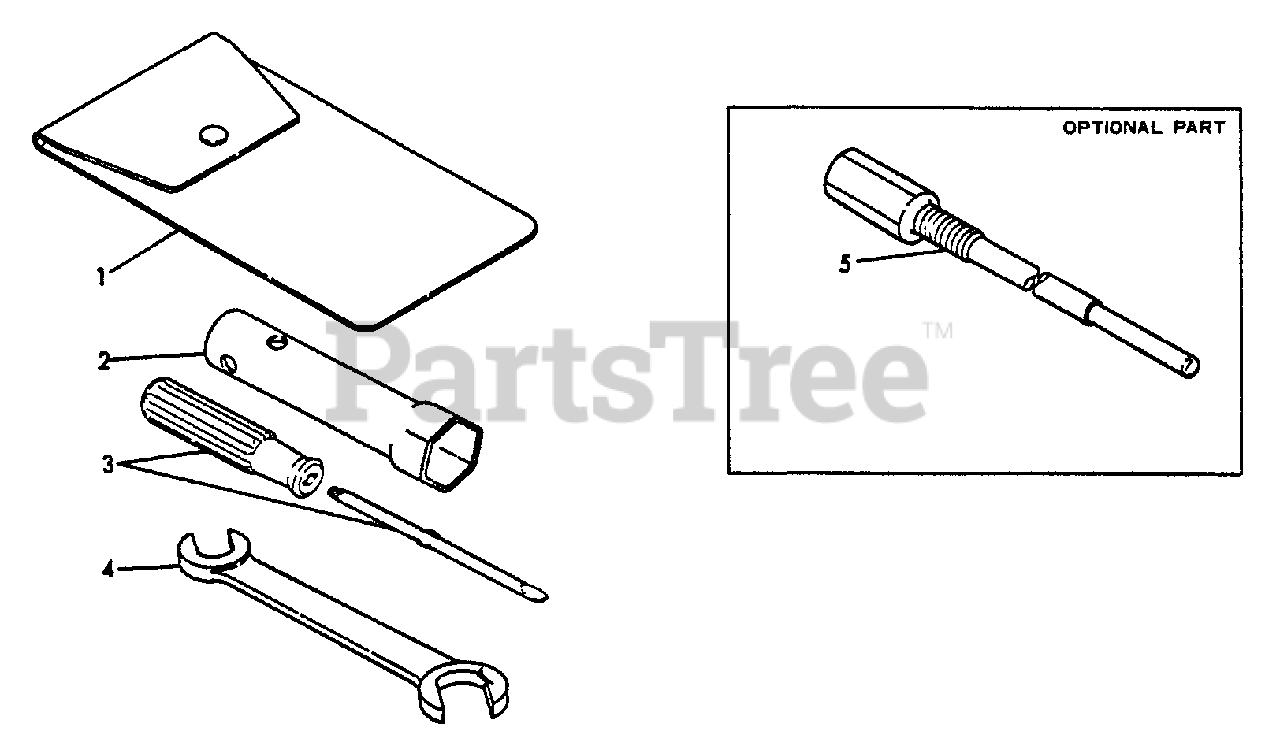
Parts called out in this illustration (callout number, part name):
1	BAG, TOOL
2	SOCKET WRENCH - 21mm
3	SCREWDRIVER
4	SPANNER - 10X12mm
5	REMOVER, ROTOR
